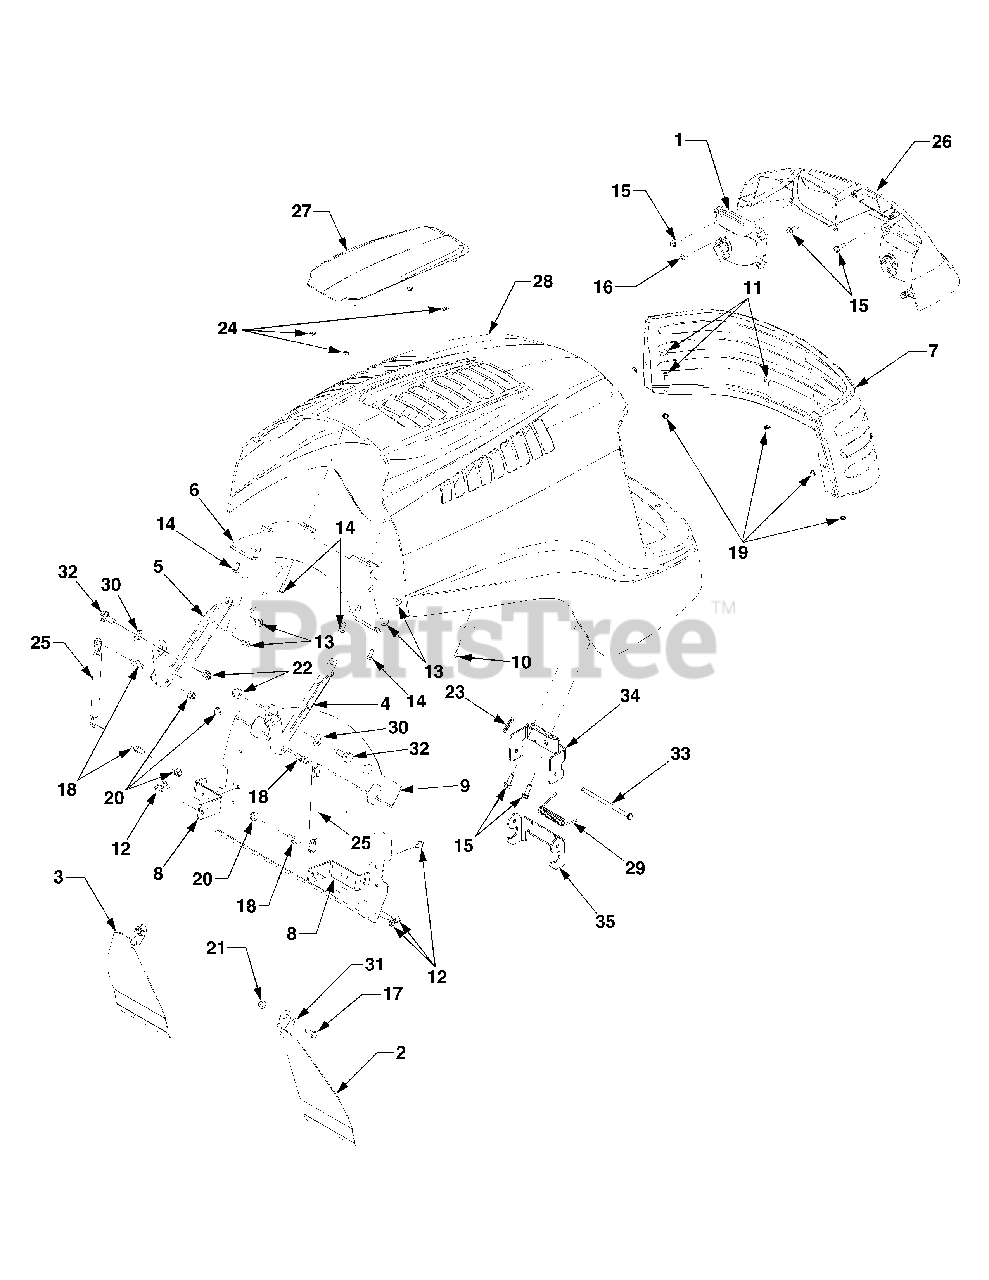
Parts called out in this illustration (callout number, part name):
1	Headlight Assembly
1	Bulb Assembly, Headlight
2	Shield, Running Board LH
3	Shield, Running Board RH
4	Bracket, Hinge, RH
5	Bracket, Hinge, LH
6	Bracket, Hood Mounting
9	Shield, Lower Heat
10	Screw, Hex Wash Hd, #8-18 x .375
11	Screw, Truss Hd, 10-24 x .5
12	Screw, Hex Wash Hd Tapp 1/4-20 x .5
13	Screw, Hex Wash Hd Tapp 5/16-18 x .5
14	Screw, Hex Cap 1/4-20 x .62 GR5
15	Screw, Hex Wash. Hd. 1/4-20 x .75
16	Screw, Truss Phil. Hd. 12-16 x .75
17	Screw, Hex Cap, 1/4-20 x .75 GR5
18	Stud, Cylinder, 5/16-18 Thrd
19	Nut, Hex Sems, 10-24
20	Nut, Hex Insert Flange Lock, 5/16-18
21	Nut, Hex Insert Flange Lock, 1/4-20
22	Nut, Hex Insert Flange Lock, 3/8-16
23	Pin, Internal Cotter
24	Nut, Push, .25 ID
25	Cylinder, Gas Spring
26	Bezel, Headlight
27	Cover, Hood
28	Hood Service Kit
28	Hood
29	Spring, Torsion
30	Washer, Flat, .51 x 1.0 x .060
31	Washer, Flat, .26 x .72 x .060
32	Screw, Shoulder, .5 x .27 Lg 3/8-16
33	Rod, .25 x 4.55
34	Plate, Latch
35	Bracket, Latch Pivot
